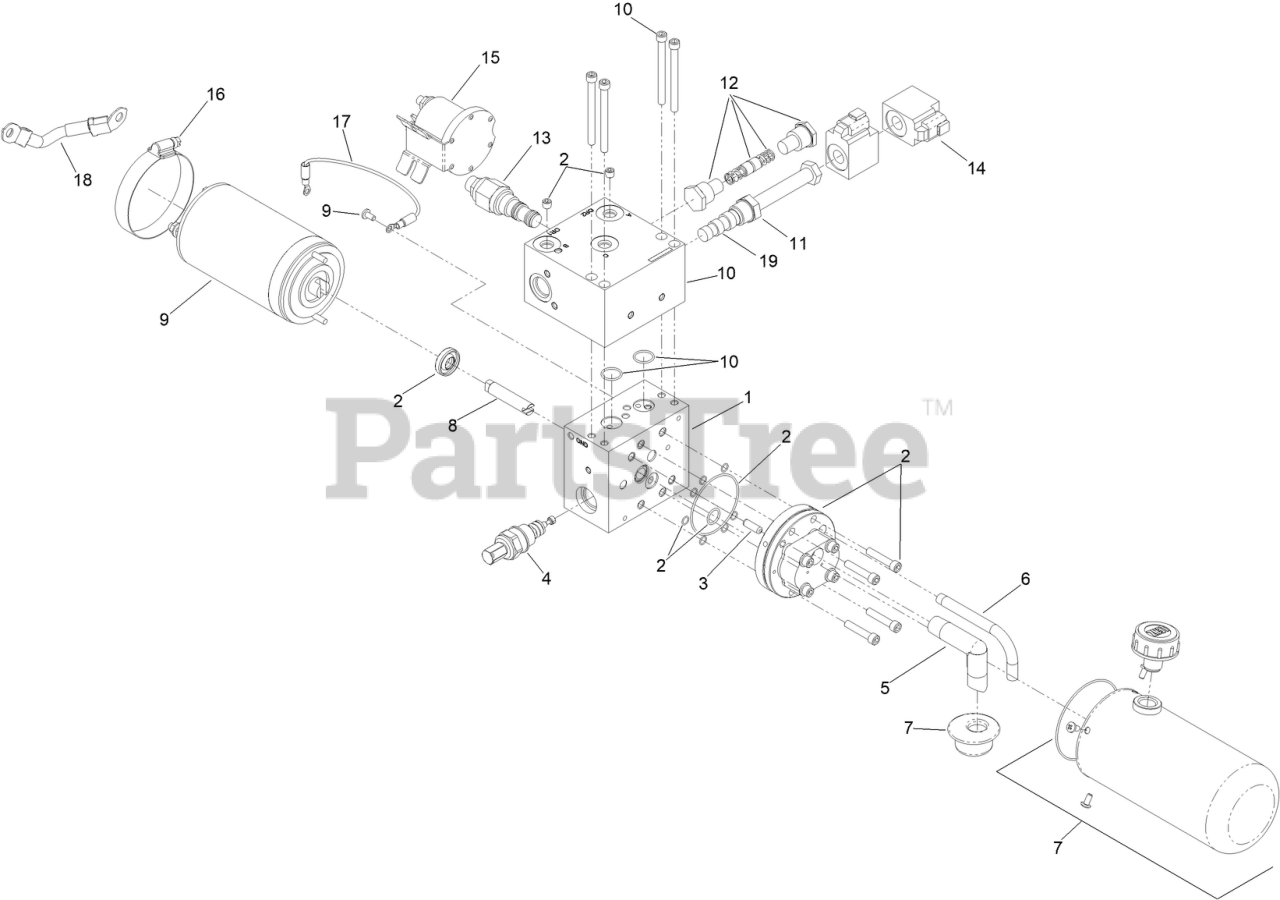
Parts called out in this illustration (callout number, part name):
1	BASE ASSY, M3298, 3.0 MTR
2	P ASSY,KIT,I,M3298,-100
3	PIN, DOWEL, 1/4 X 3/4
4	VALVE,RELIEF,VM01,210-320 BAR
5	INLET TUBE,BU
6	TUBE, RETURN, 90DEG, 1/8NPTF
7	PARTS KIT,RESV,STL,3.375 X 7.0
8	SHAFT, INTERMEDIATE, MICRO, DC
9	MOTOR, DC, 12V, 3IN, 1 TERM
10	PARTS KIT,MANIFOLD ASSY,M3200
11	CARTRIDGE, 4W/3P, 3000PSI, MC, #8
12	PARTS KIT,DBL PO CK VLV,4INMAN
13	COUNTERBALANCE, 08, 5000-PSI
14	COIL, 12VDC, 16W, RECT, DEUTSCH
15	POWER UNIT SOLENOID KIT,ATV/MS-UTV
16	CLAMP,HOSE,WORM GR,2.3-3.25
17	WIRE ASSY, CNTRL, 16AWG, HS, RING
18	CABLE, INSULATED, W/LUGS, 5IN, 6GA
19	PARTS KIT, SEAL, 4W/3P VALVE
99	RUBY TRAN-1 GAL
99	CAP-POWERUNIT
